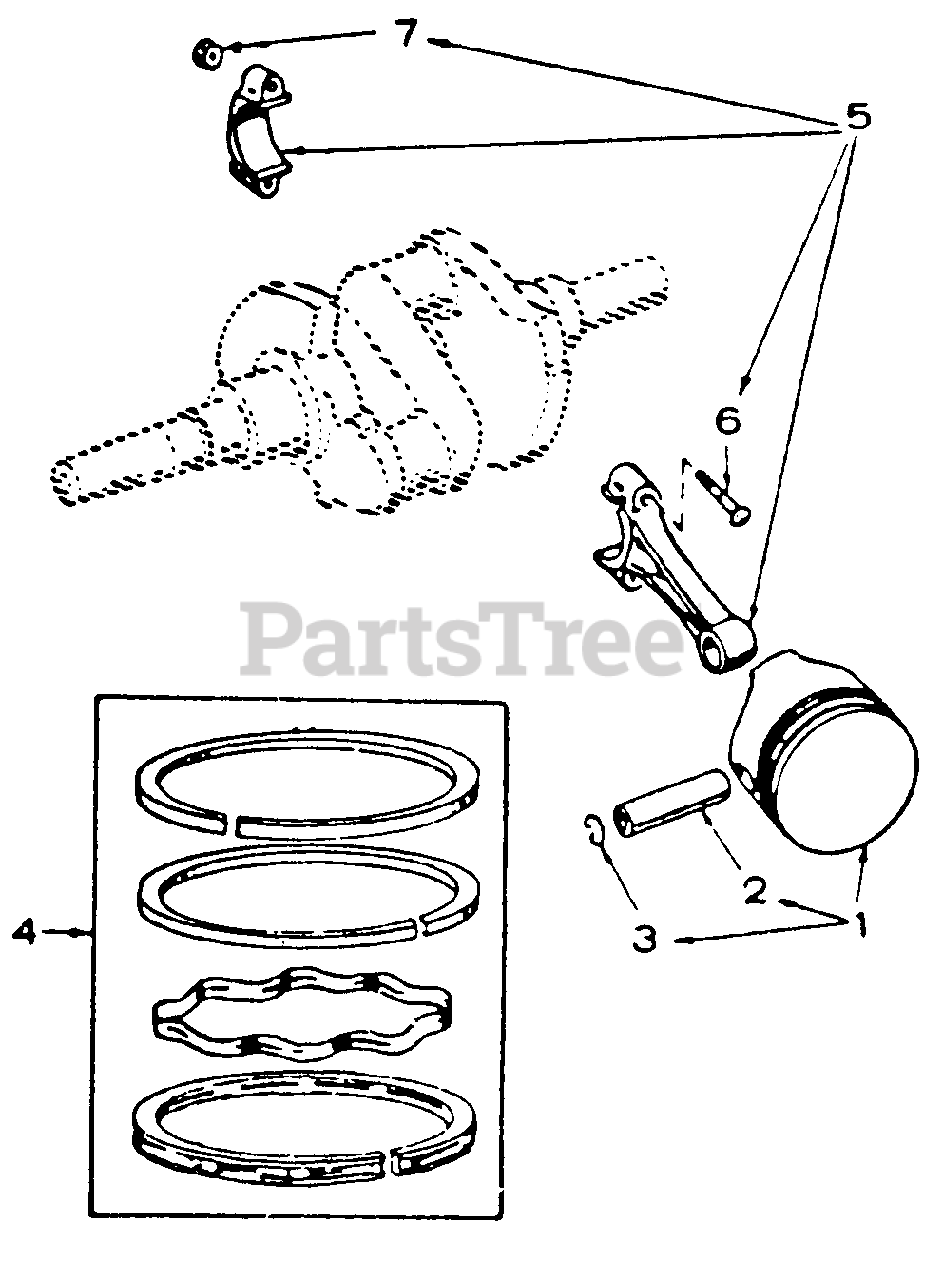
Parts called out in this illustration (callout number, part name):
1	Set, Piston & Pin, Std
2	Pin, Piston
3	Retainer, Piston Pin
4	Ring Set, Std
5	Rod, Connecting, Std
6	Bolt, Connecting Rod
